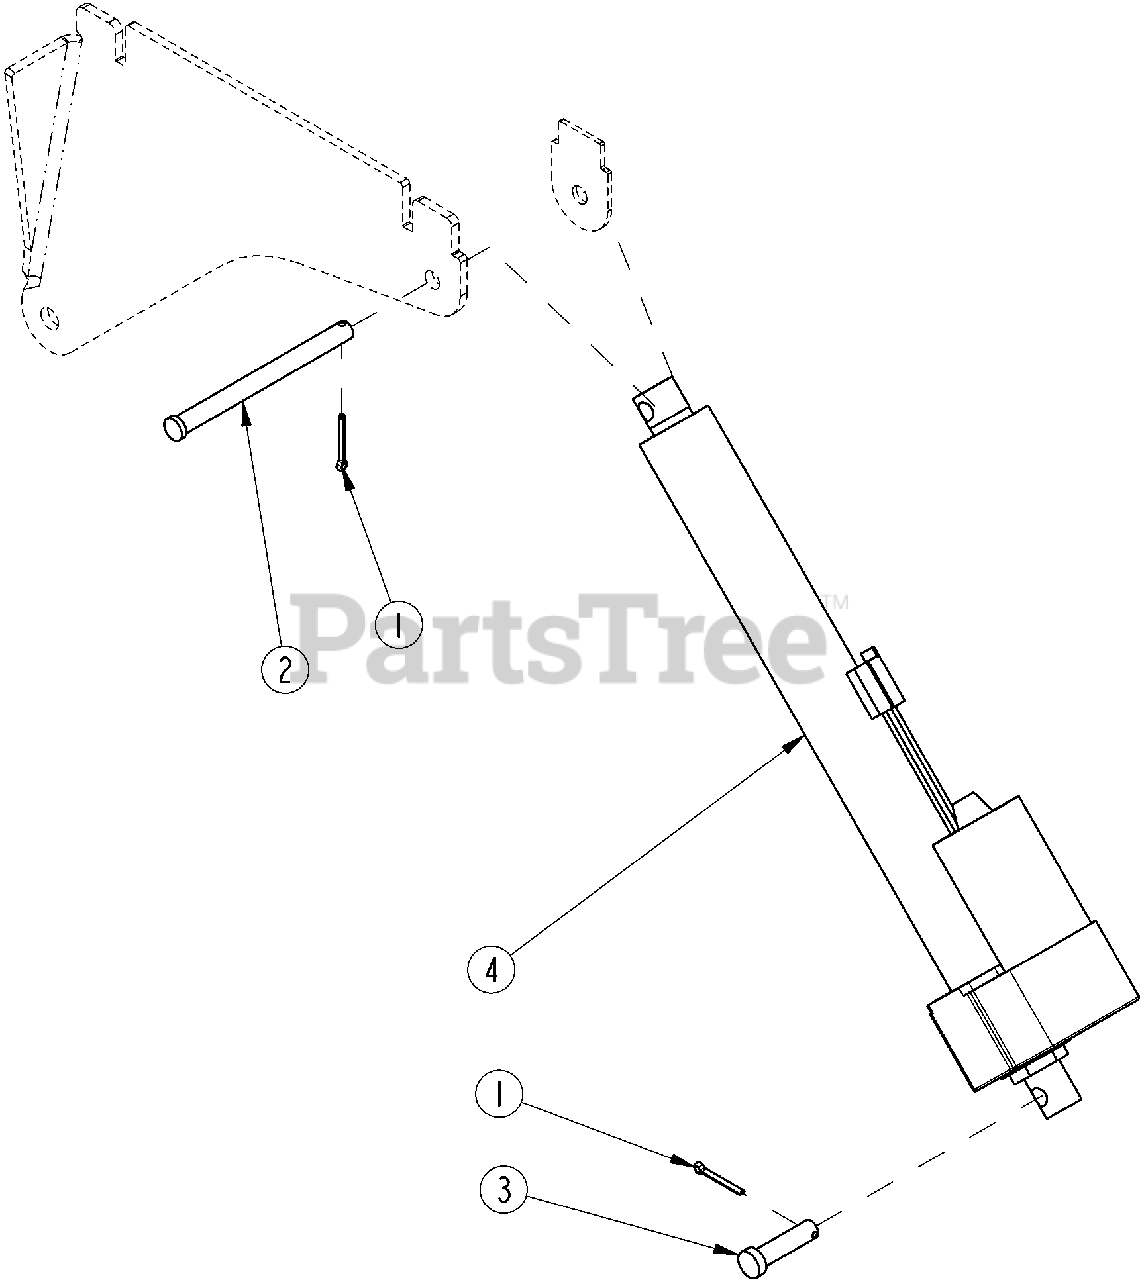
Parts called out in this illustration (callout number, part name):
1	PIN COTTER 5/32 X 1 1/4 LG
2	PIN CLEVIS 1/2 X 6
3	PIN CLEVIS 1/2X1 49/64 USABLE
4	ELECT. LINEAR ACTUATOR 12"STRK
